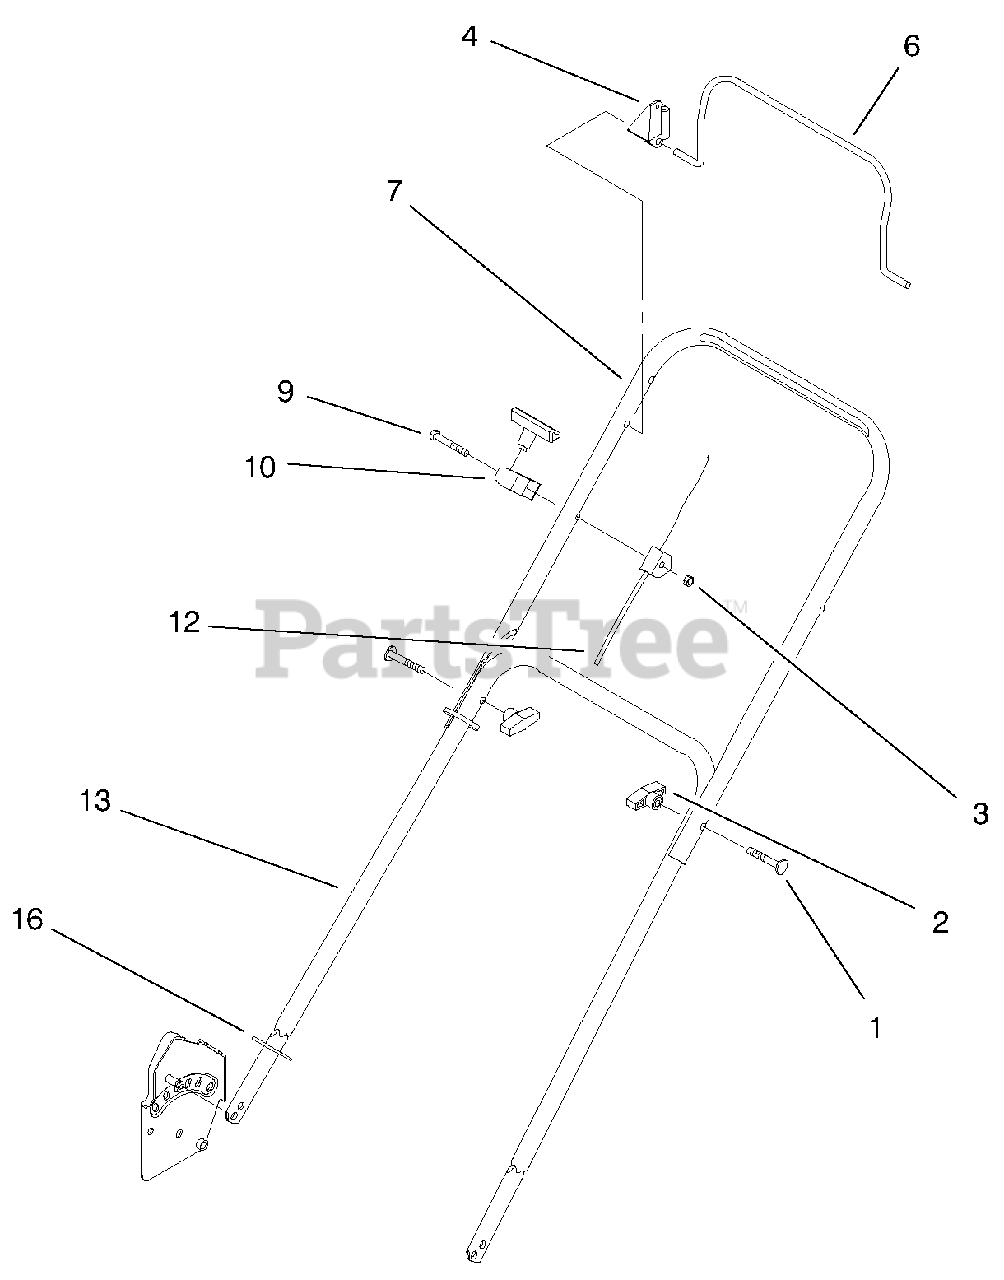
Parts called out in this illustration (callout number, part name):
1	Screw-HH
2	Knob-Handle
3	Nut-Lock Ni
4	Stop-Pivot
6	Bail-Brake
7	Handle-Upper
9	Screw-HH
10	Rope-Guide
12	Cable-Flywheel Brake Hi Wheel 4 Cyc
13	Section-Lower Handle
16	Guard-Handle
